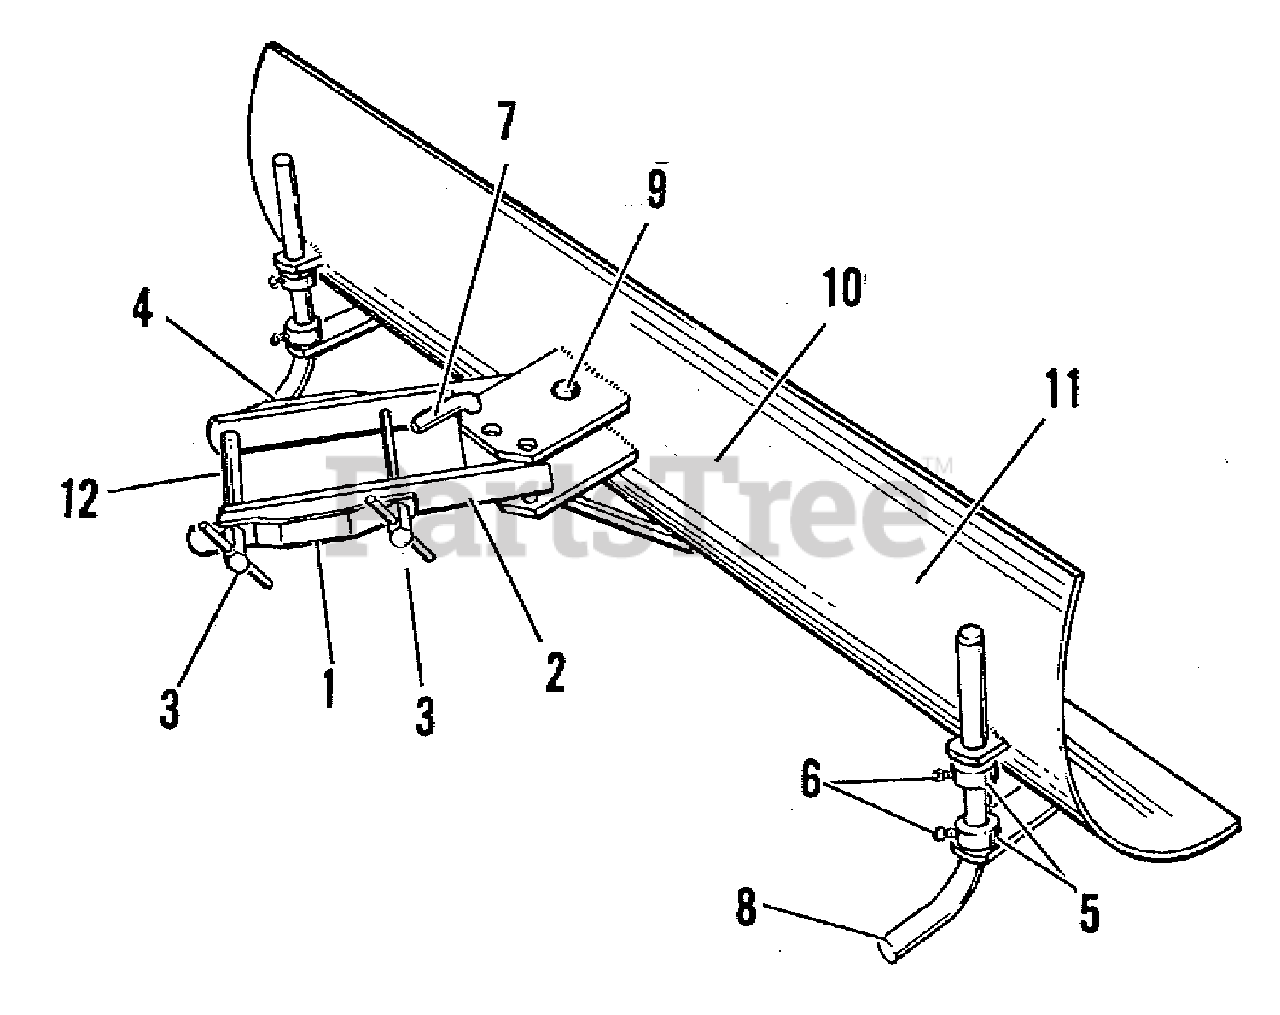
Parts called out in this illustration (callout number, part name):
1	HITCH SIDE PLATE
2	PUSH BAR ASSEMBLY
3	WING NUT, Complete
4	CLAMP, Hitch
5	COLLAR, Set
6	SCREW, Set, 5/16-18NC x 1/2" Lg.
10	BLADE ASSEMBLY, 30"
11	BLADE ASSEMBLY, 42"
